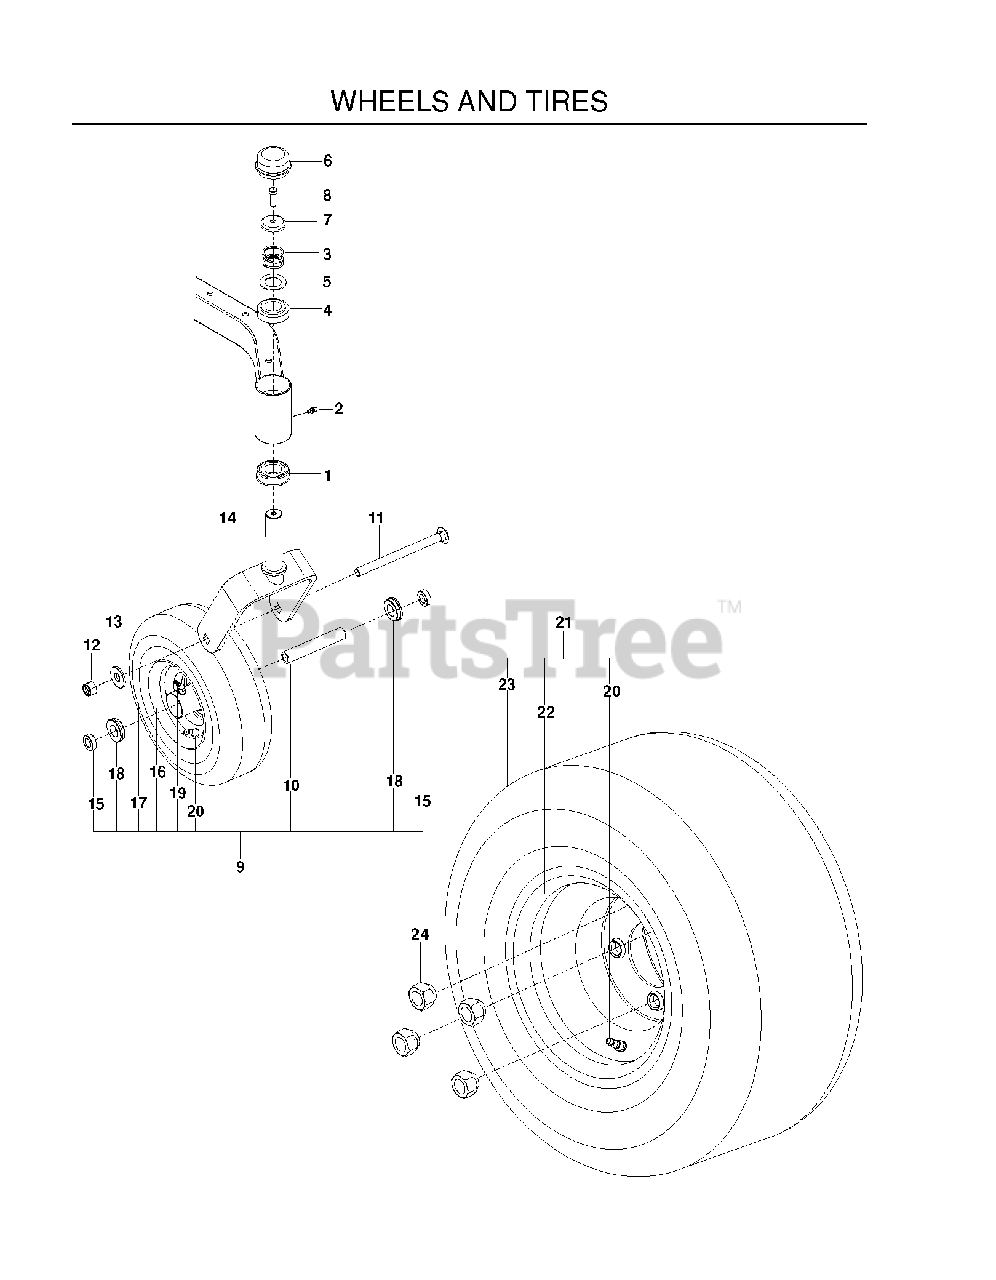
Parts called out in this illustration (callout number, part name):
1	BEARING FLANGED
2	ZERK, 3/16, DRIVE IN
3	SPRING, CASTER
4	BUSHING, CASTER
5	WASHER, 1.025 ID X 1.64
6	GREASE CAP
7	CASTER.PLUG
8	HCS 5/16C X 1
9	TIRE COMPLETE
11	RHSNB 1/2-13 X 6.50 GR2 ZD
12	NUT 1/2-13 HEX NYLOC ZD
13	WASH USS FLAT 1/2
14	CASTER DK BLUE
15	SPACER, 5/16"
17	TIRE - 410/350-5
18	BEARING RETAINER
19	ZERK
20	VALVE STEM TR-412
21	TIRE ASM, 20 X 8-8
22	RIM.8X7.W/8".OFFSET
23	Tire 20 X 8, Turf
24	LUG NUT 1/2F
